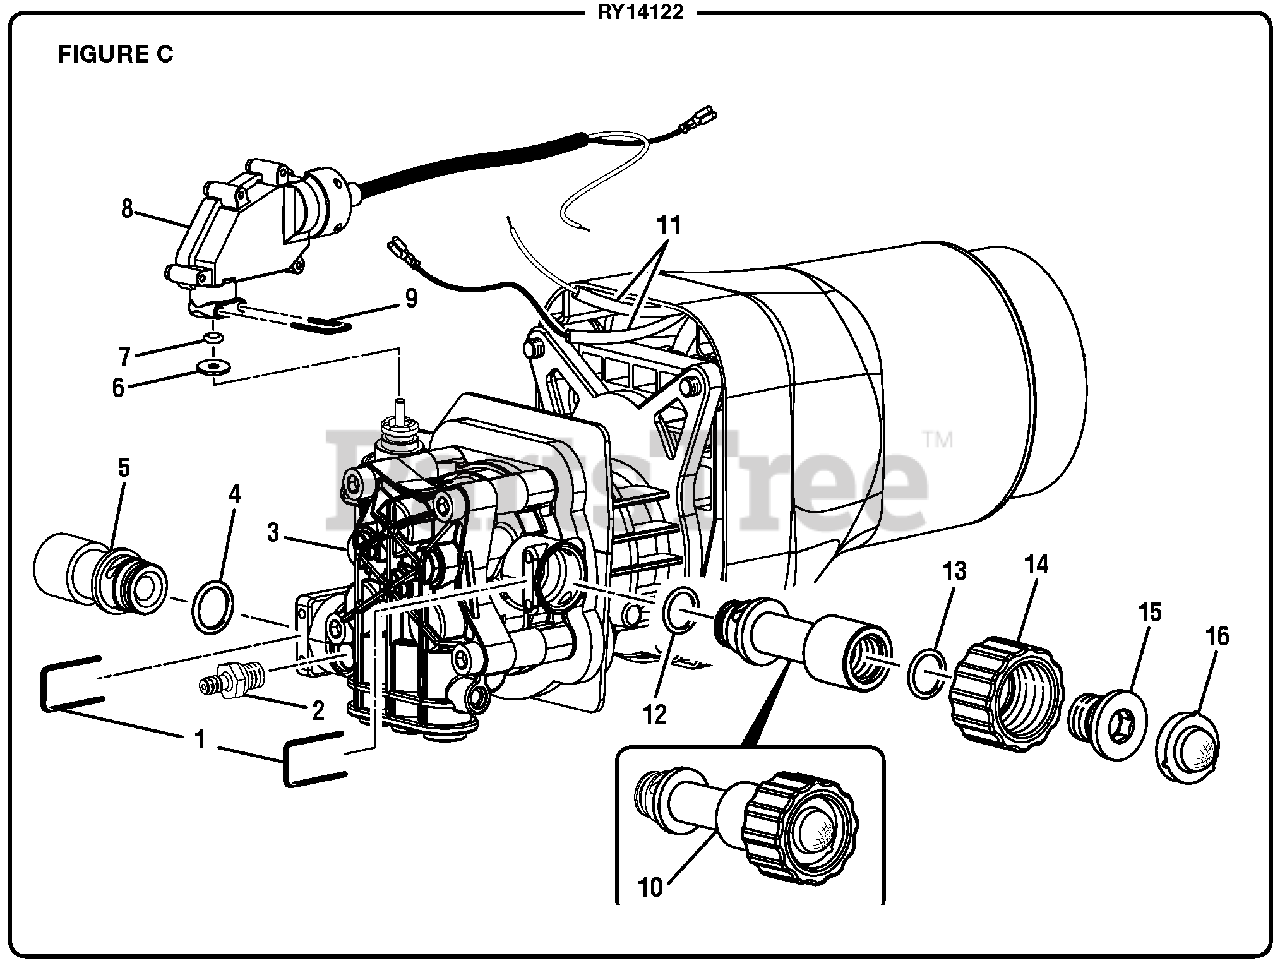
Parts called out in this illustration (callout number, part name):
2	Detergent Nipple Assembly
3	Motor and Pump Assembly
5	Outlet Tube Assembly
6	Washer (Brass)
7	O-Ring
8	Pressure Switch
14	Water Inlet Connector
15	Water Inlet Screw Nut
16	Water Inlet Filter
17	Inlet Tube Assembly
